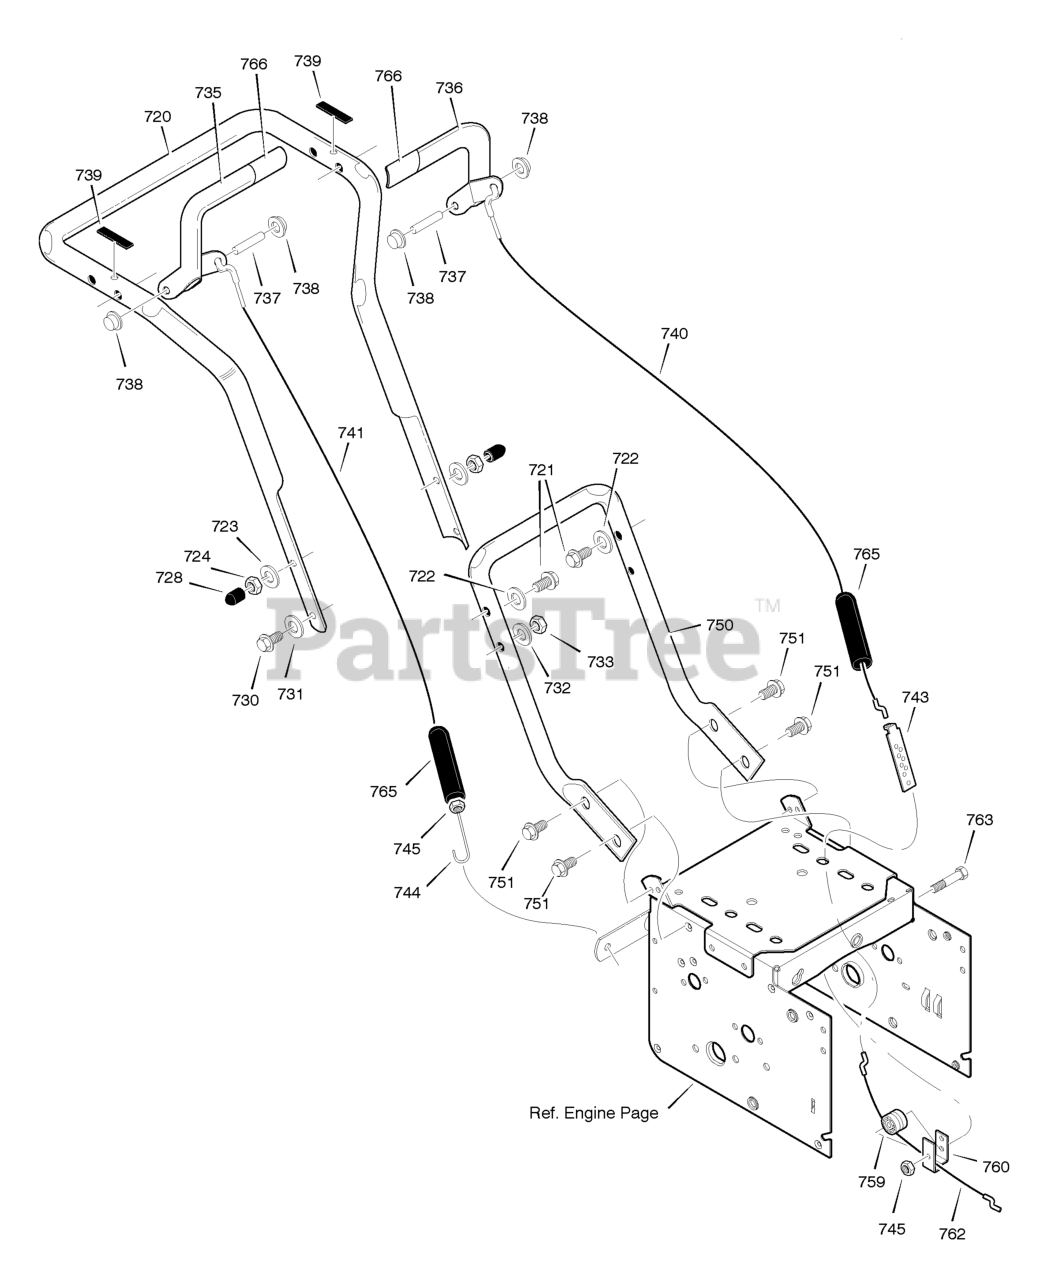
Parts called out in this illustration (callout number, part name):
720	HANDLE, UPPER
721	SCREW, 3/8- 16 X 3
722	WASHER, FLAT
723	WASHER
724	NUT, 3/8- 16
728	STOP, PLASTIC
730	SCREW, 3/8- 16 X 2
731	WASHER, FLAT
732	WASHER
733	NUT, 3/8- 16
735	HANDLE, RIGHT
736	HANDLE, LEFT
737	PIN, PIVOT CLUTCH
738	NUT, PUSH ON CAP
739	BUMPER, RECTANGLE
740	CABLE, DRIVE
741	CABLE, AUGER CLUTCH
743	BRACKET, CABLE ADJUSTER
744	SPRING, AUGER CLUTCH
745	NUT, 1/4- 20
750	HANDLE, LOWER
751	SCREW, TAP 5/16-18 X .75
759	SPOOL-CABLE, AUGRT CLUTCH
760	BRACKET, CABLE SPOOL YZ
762	CABLE, LOWER DRIVE 12"
763	BOLT, HEX 1/4-20 X 1.5
765	BOOT, CLUTCH SPRING
